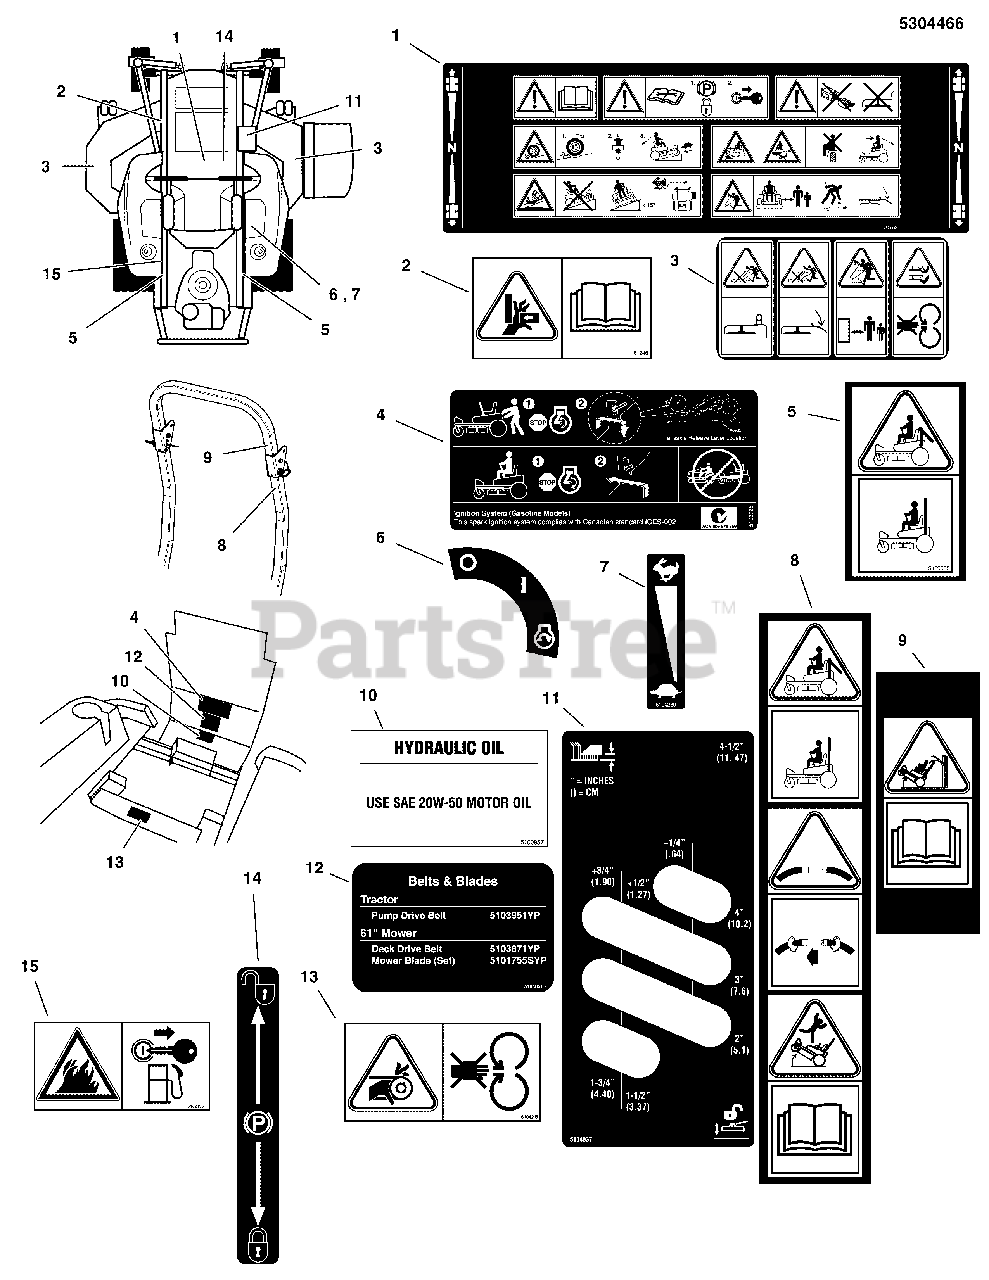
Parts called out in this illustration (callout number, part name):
1	DECAL, MAIN SAFETY, ANSI CE
2	DECAL, PINCH POINT, CE
3	DECAL, DISCHARGE
4	DECAL, TRANSAXLE RELEASE, 600/700
5	DECAL, WARNING, ROLL BAR, CE
6	DECAL, IGNITION SWITCH
7	DECAL, THROTTLE CONTROL
8	DECAL, SAFETY, CE ROPS
9	DECAL, SAFETY, CE ROPS, OBS
10	DECAL, HYDRAULIC OIL, SAE 20W50
11	DECAL, CUT HEIGHT, SNAPPER 550
12	DECAL, BELT & BLADE, 550Z 52/61
13	DECAL, CE DANGER
14	DECAL, FIRE ANSI EXPORT
15	DECAL, PARKING BRAKE SYMBOLS
